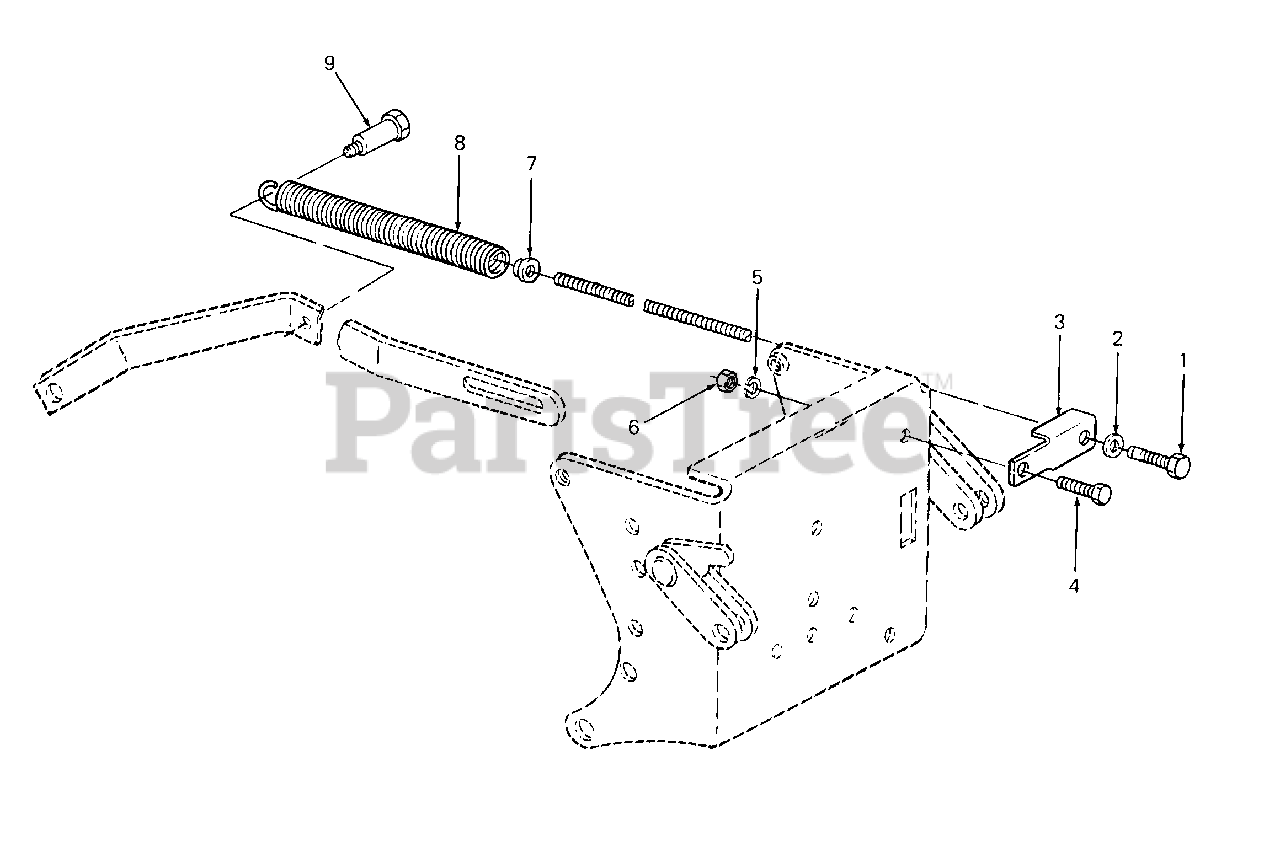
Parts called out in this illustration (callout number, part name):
1	Screw, Hex Special
2	Washer, Flat, .40 X .88 X .06 HDN
3	Anchor, Spring
4	Screw, Hex Cap, 7/16-14 X 1.0 Lg GR5
5	Washer, Lock, 7/16
6	Nut, Hex Center Lock, 7/16-14
7	Insert, Spring
8	Spring, Lift Assist
9	Bolt, Shoulder, 1/2-13 X 2.5 Lg
